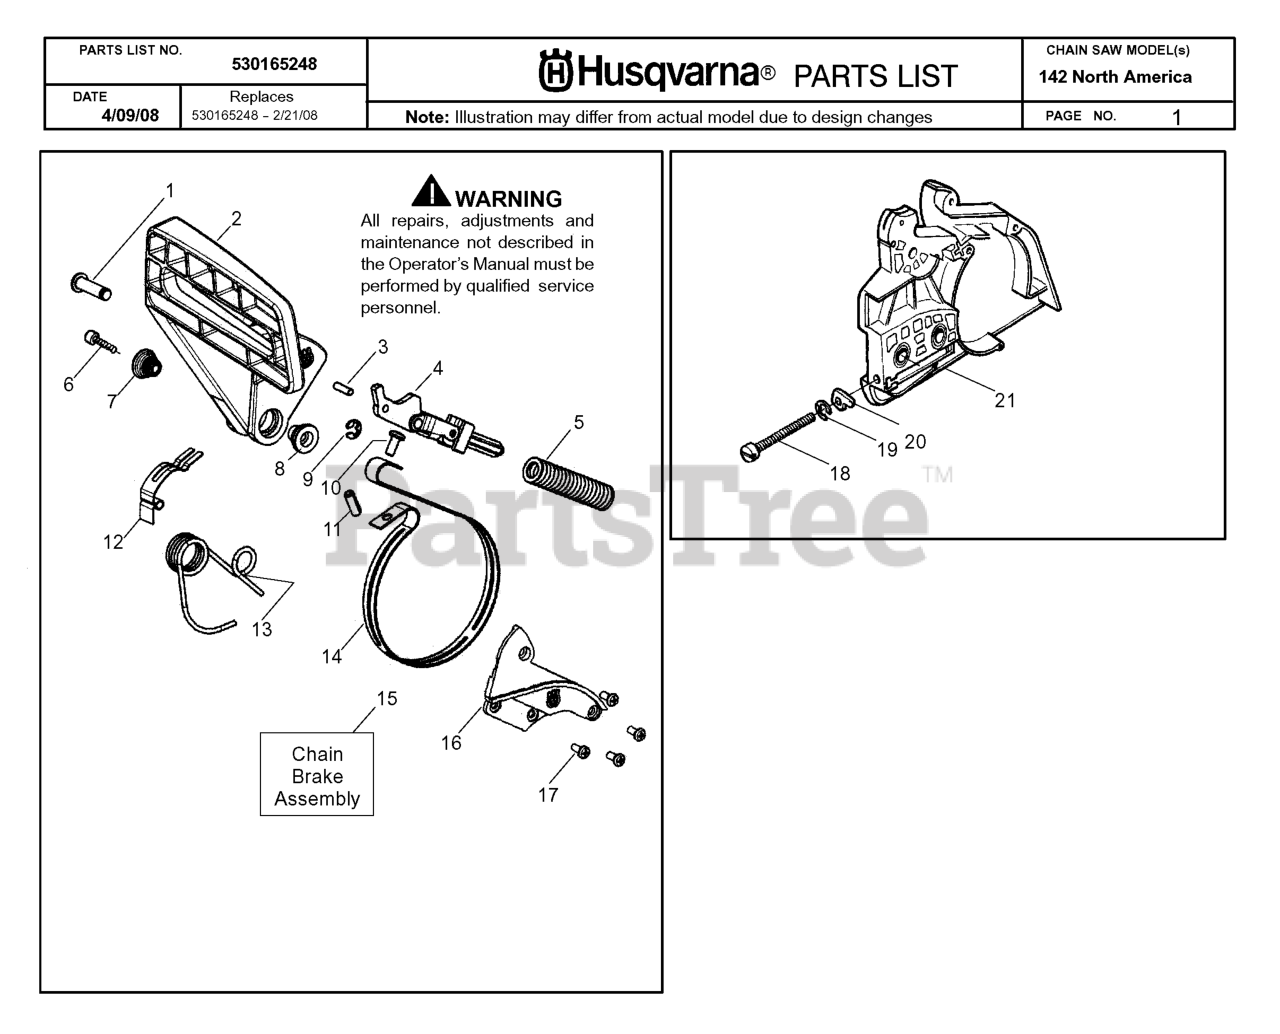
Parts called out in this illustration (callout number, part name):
4	FRONT LINK ASSY
5	%COMPRESSION SPRING
7	JOURNAL, RIGHT
8	SHAFT PIVOT
10	SCREW
12	SPRING-POSITION
13	SPRING,BRK HDL 36/41
14	BRAKE BAND
15	CHAIN BRAKE ASM.
16	CHAIN BRAKE COVER
17	SCREW
18	BAR ADJUSTING SCREW
20	ADJUST PIN,BAR 36/41
21	CLUTCH COVER
